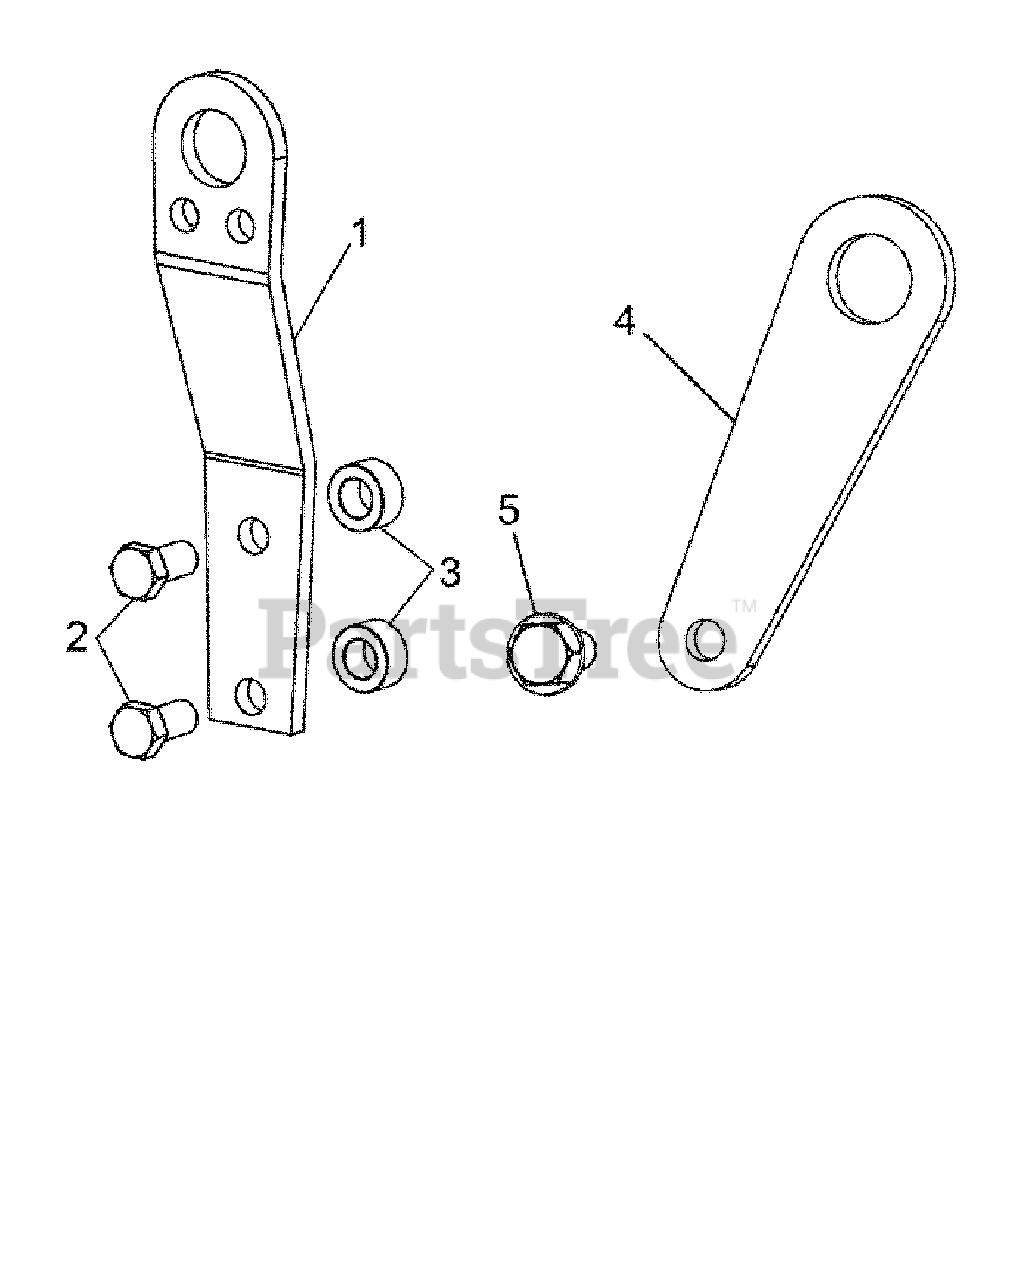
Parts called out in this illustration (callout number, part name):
1	BRACKET
2	BOLT
3	SPACER
4	STRAP
5	SCREW
